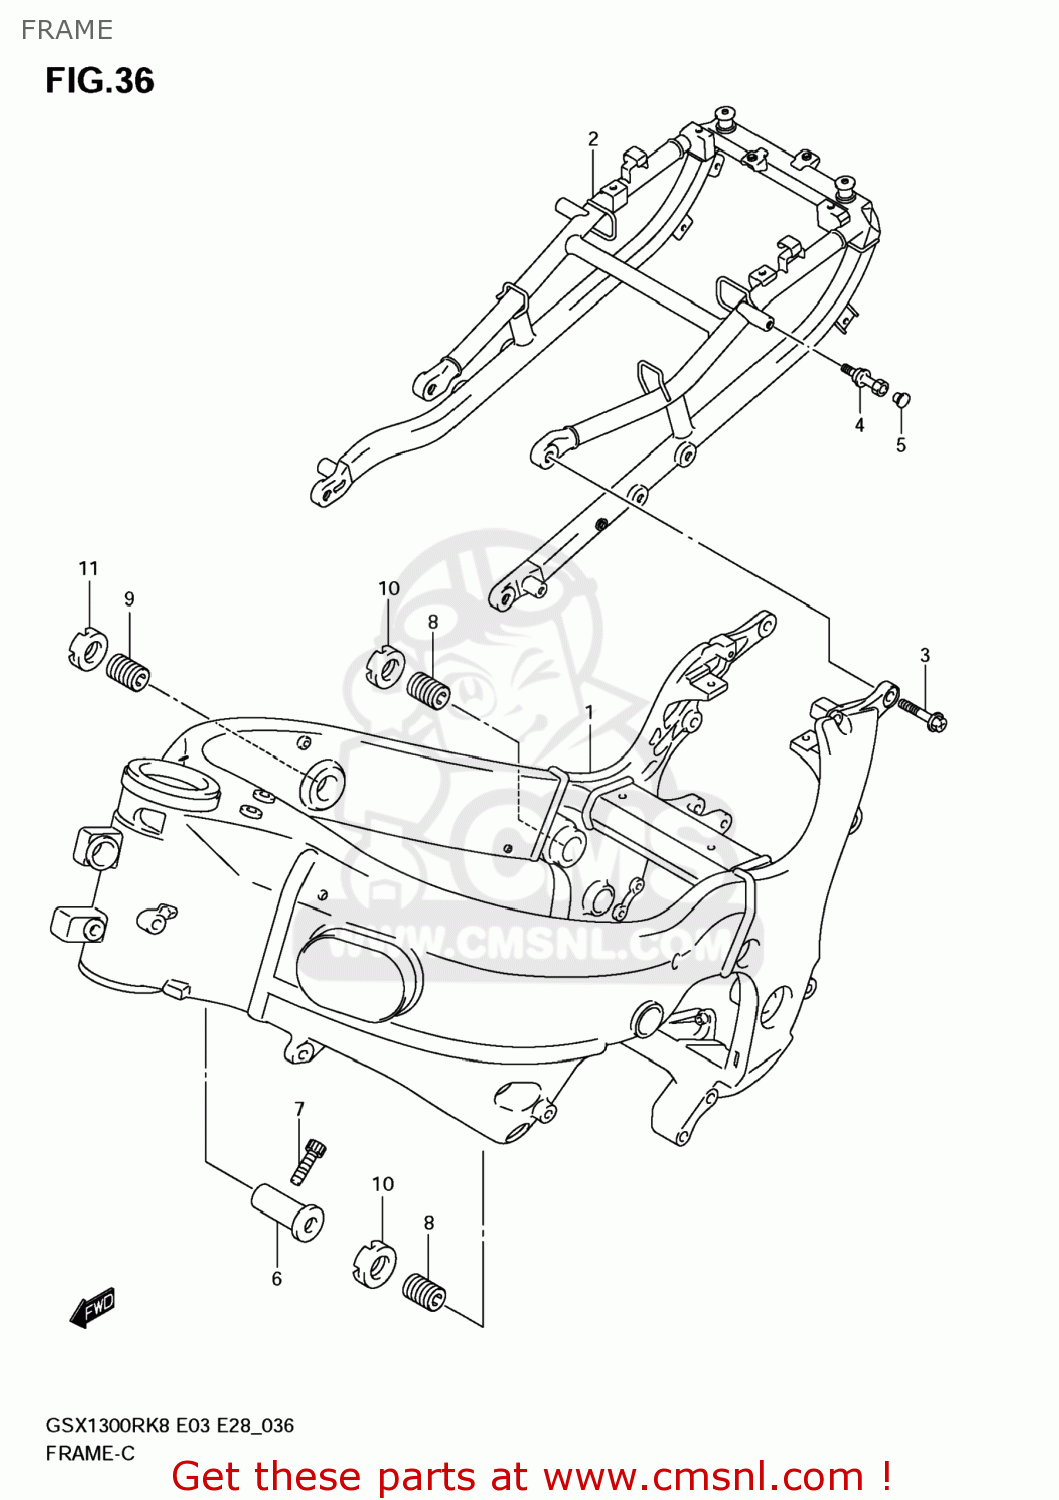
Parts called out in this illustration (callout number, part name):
1	FRAME
2	RAIL,SEAT
3	BOLT(10X30)
4	HOOK,SEAT RAIL
5	CAP(OD:10)
6	SPACER,ENGINE MTG
7	BOLT(8X30)
8	BOLT,CRANK CASE ADJUST
9	BOLT,CRANK CAS
10	NUT,CRANK CASE ADJUST
11	NUT,CRANKCASE ADJUST
